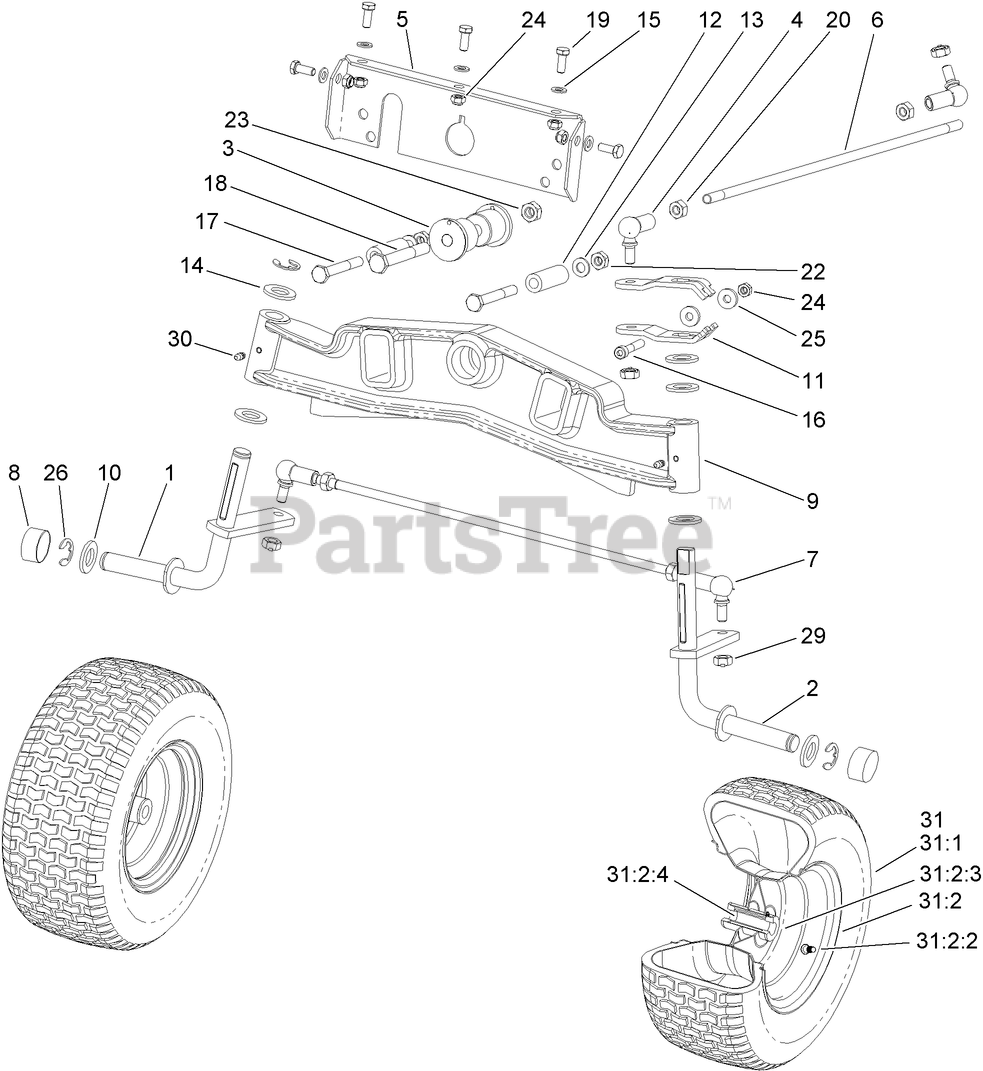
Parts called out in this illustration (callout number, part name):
1	SPINDLE-FRONT, RH
2	SPINDLE-FRONT, LH
3	BUSHING-AXLE, FRONT
4	JOINT-BALL, ANGLE
5	PLATE-AXLE
6	LINK-DRAG
7	ROD-TIE, FRONT AXLE
8	CAP-HUB
9	AXLE-FRONT
10	WASHER
11	LEVER-SPINDLE, STEERING
12	SPACER
13	WASHER-FLAT
14	WASHER-FLAT
15	WASHER-PLAIN
17	SCREW-HH
18	SCREW-HH
19	SCREW-HH
22	NUT-LOCK
23	NUT-LOCK, HEX NI
24	NUT-LOCK, NI
25	Washer-Flat
26	CLIP-SPRING
29	NUT-LOCK, NI
30	FITTING-GREASE
31	WHEEL ASM
31:2	WHEEL ASM
31:2:2	Valve-Tire
31:2:3	BEARING-WHEEL
31:2:4	Spacer-Wheel
